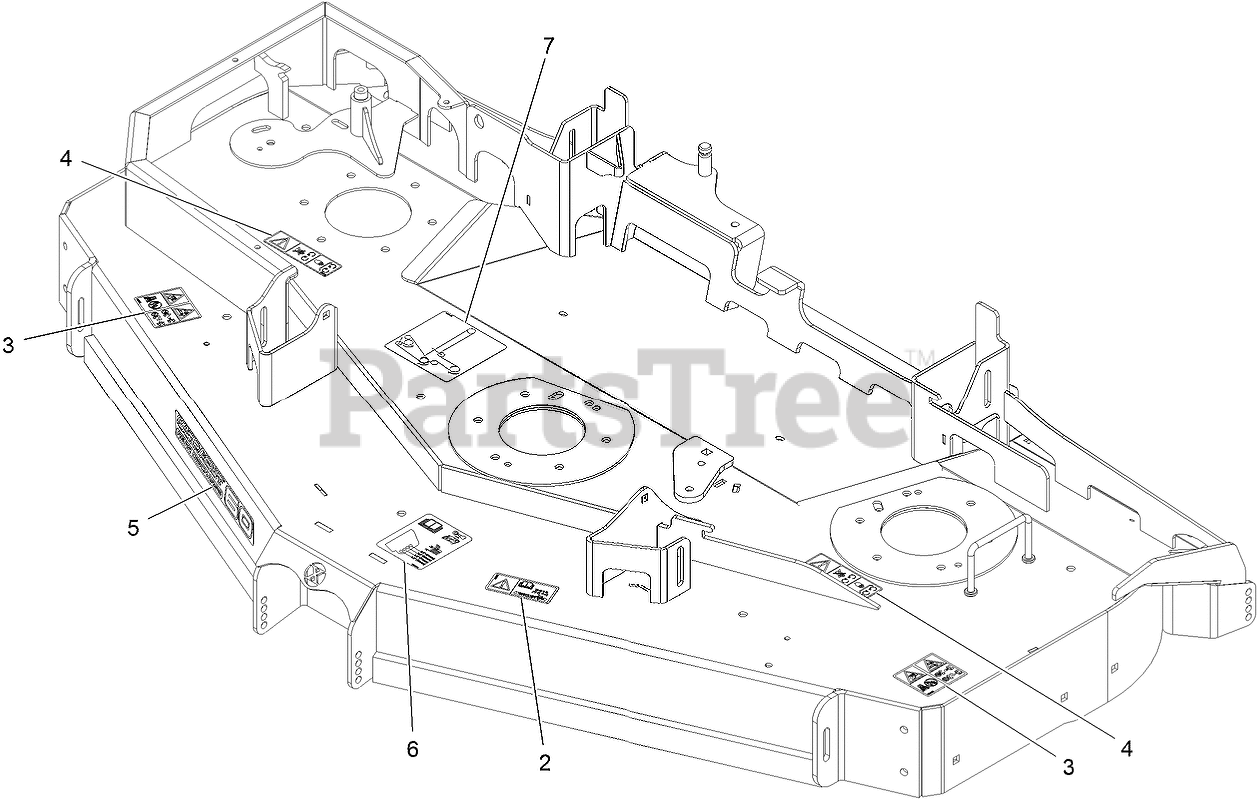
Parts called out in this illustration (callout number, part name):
2	DECAL-BOLT TORQUE
3	DECAL-DANGER, THROWN OBJECT
4	DECAL-COVER, MISSING
5	Decal, 60Rd
6	DECAL-ROLLER, ANTI-SCALP
7	DECAL-ROUTING, BELT
